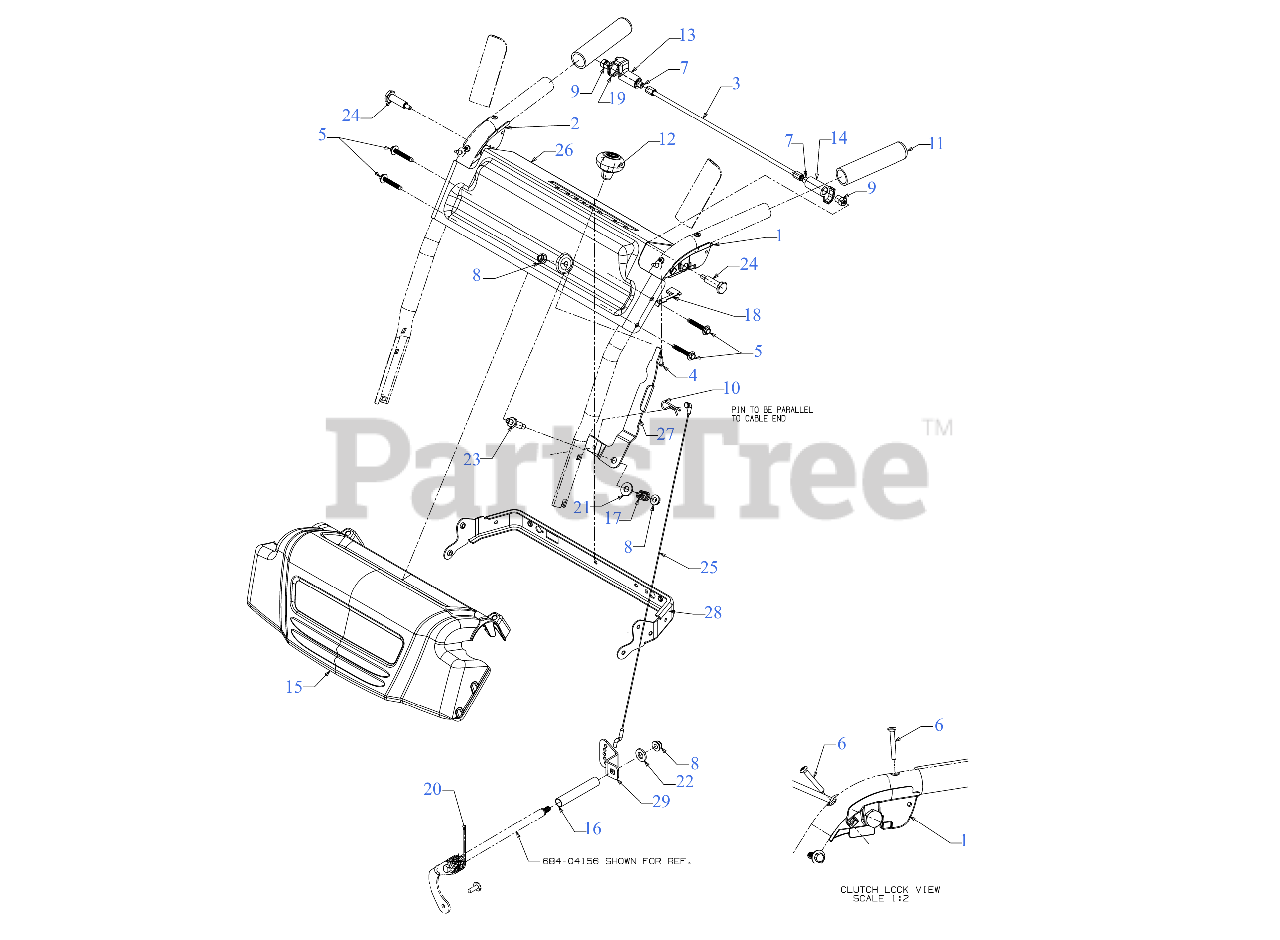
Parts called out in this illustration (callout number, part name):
1	CLUTCH LOCK HANDLE ASSEMBLY (LH)
2	CLUTCH LOCK HANDLE ASSEMBLY (RH)
3	PIVOT ROD
4	SCREW #8-16 x .50
5	SCREW 1/4-20 x 1.625
6	SCREW #10-24 x 1.375
7	SCREW 1/4-20 x .50
8	FLANGE LOCK NUT 5/16-18
9	HEX NUT W/PATCH
10	INTERNAL COTTER PIN
12	SHIFT KNOB
13	LOCK PLATE
14	CLUTCH LOCK CAM
15	PANEL HANDLE COVER
16	COVER .505 X .635 X 3.64
17	COMPRESSION SPRING
18	CLUTCH SPRING
19	TORSION SPRING
20	TORSION SPRING
21	FLAT WASHER .385X.870X.090
22	FLAT WASHER
23	SHOULDER BOLT
24	SHOULDER SCREW .437 x 1.345 1/4-20
25	SPEED SELECTOR CABLE (STEEL)
28	HANDLE SUPPORT BRACKET (POWDER BLACK)
29	SPEED SELECT SHIFT BRACKET
